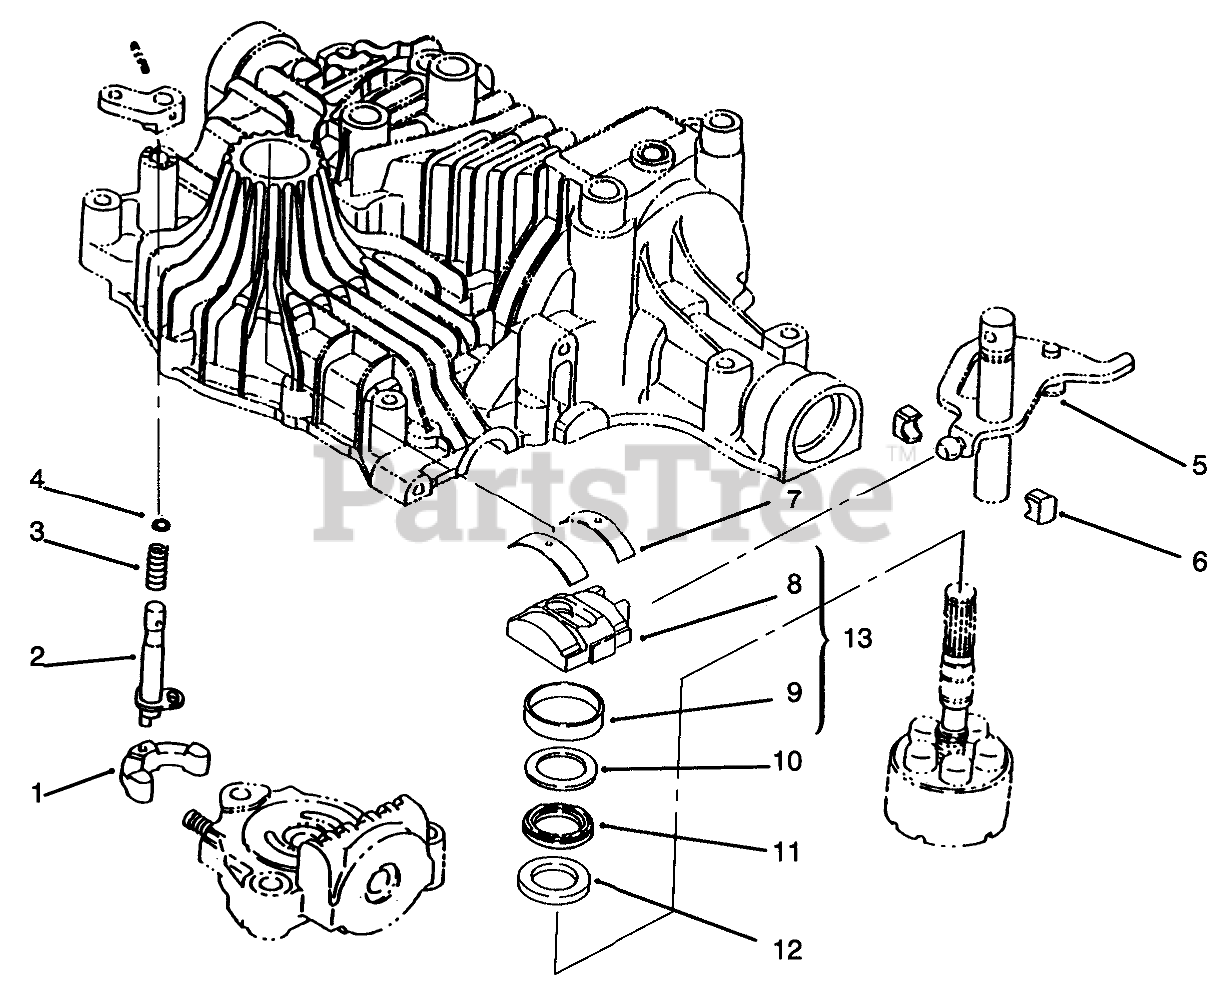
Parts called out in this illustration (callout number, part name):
1	Arm (Only On: 72043, 72063, 72103)
2	Shaft-Bypass (Only On: 72043, 72063, 72103)
3	Spring (Only On: 72043, 72063, 72103)
4	Packing (Only On: 72043, 72063, 72103)
5	Block Set INCL 6 (Only On: 72043, 72063, 72103)
7	Thrust Metal (Only On: 72043, 72063, 72103)
10	Plate-Thrust (Only On: 72043, 72063, 72103)
11	Bearing (Only On: 72043, 72063, 72103)
12	Plate-Thrust (Only On: 72043, 72063, 72103)
13	Swash Plate INCL 8-9 (Only On: 72043, 72063, 72103)
